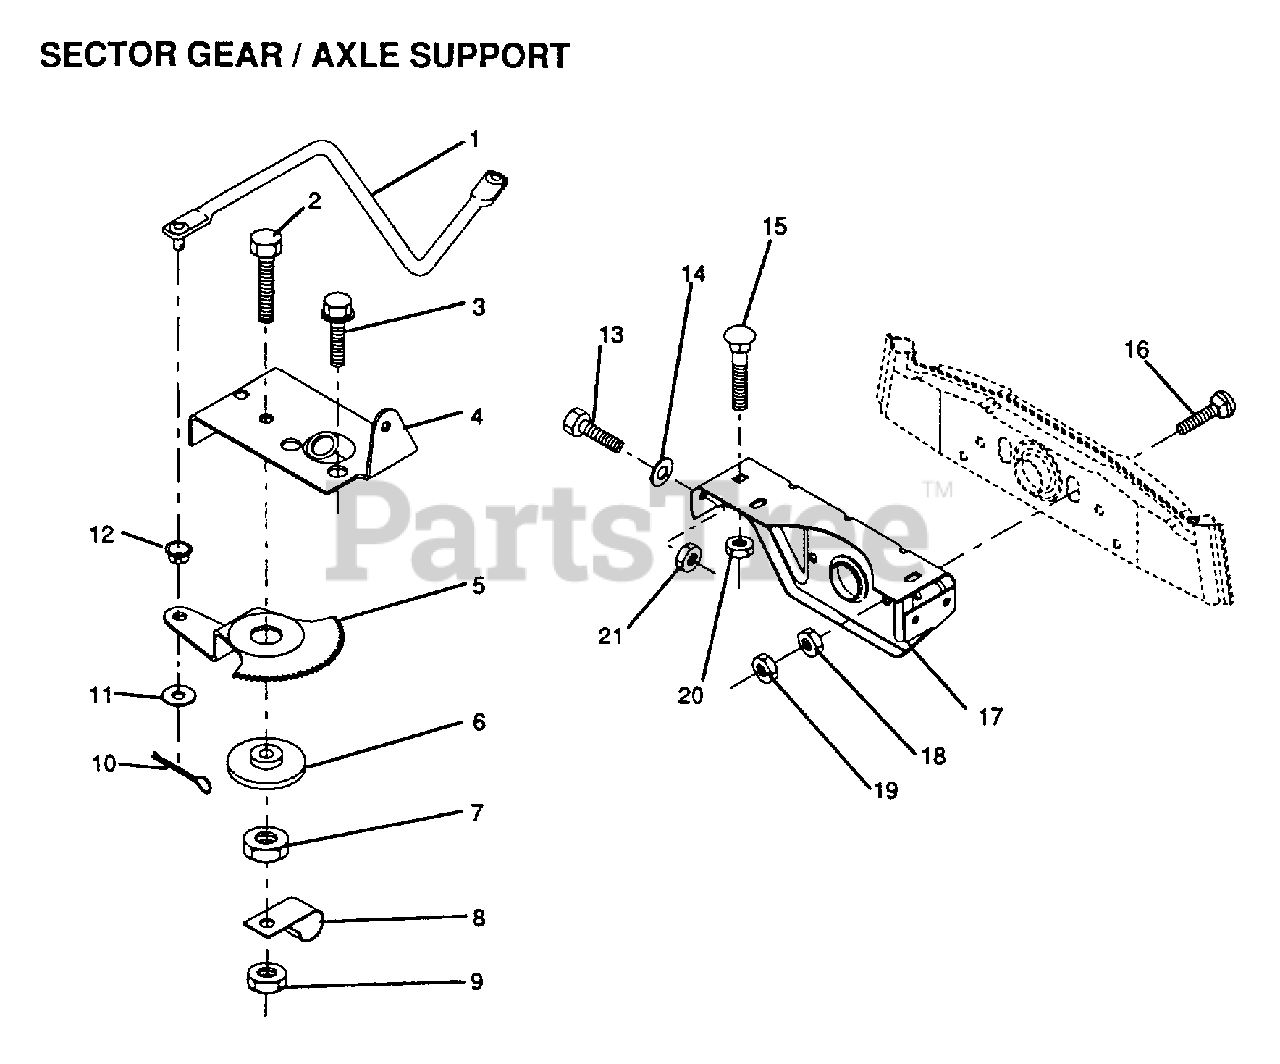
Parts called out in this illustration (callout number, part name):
2	"BOLT,HEX"
3	SCREW LT
4	"PLATE,STR SUPT"
5	GEAR SECTOR
6	BUSHING
7	NUT
9	NUT LTV
10	COTTER PIN
11	WASHER
13	BOLT
14	WASHER
15	BOLT
16	BOLT
17	"SUPT,FRT AXLE"
18	NUT.HEX.3/8-16UNC
19	LOCKNUT
